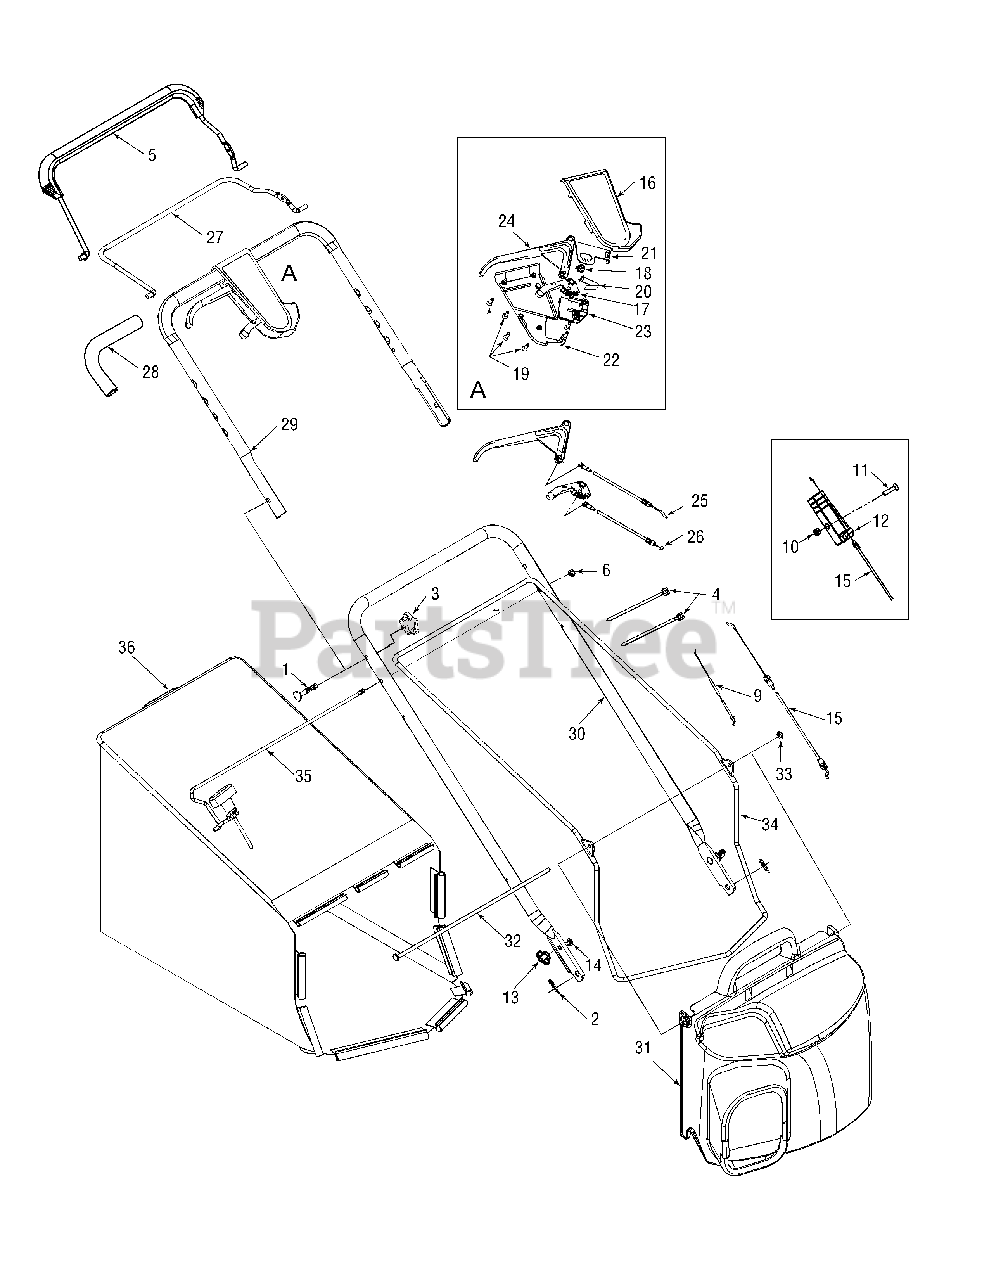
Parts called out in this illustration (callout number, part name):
1	Carriage Bolt 5/16-18 x 2.0
2	Int. Cotter Pin 5/16 DIA
3	Plastic Knob
4	Cable Tie
5	Control Bail Lever - Deluxe Black
6	Flg. Lock Nut 5/16-18 Gr. F Nylon
8	Cup. Wash. .265 ID x .75 OD x .062
9	Throttle Wire 60.0" Lg. Yellow
10	Hex Ins. Locknut 1/4-20
11	Mach. Scr. 1/4-20 x 1.319
12	Cable Bracket
13	Carriage Bolt 1/4-20 x .75
14	Wing Nut
15	Control Cable 44.75 Lg. (B&S)
16	Control Cover
17	6 Speed Shift Lever
18	3 Tooth Rack Gear Insert
19	C-sunk Tap Screw #10 x .75
20	Shift Lever Spring
21	Rack Cable Bracket
22	Control Cover
23	Control Cover
24	Control Lever
25	Pulley Cable 53" Lg.
26	Clutch Cable - 53" Lg. Orange
27	Control Bail Lever
28	Foam Grip
31	Grassbag Cover w/Label
32	Grasscatcher Pivot Rod
33	Push Cap
34	Grasscatcher Upper Frame
35	Grasscatcher Support Rod
